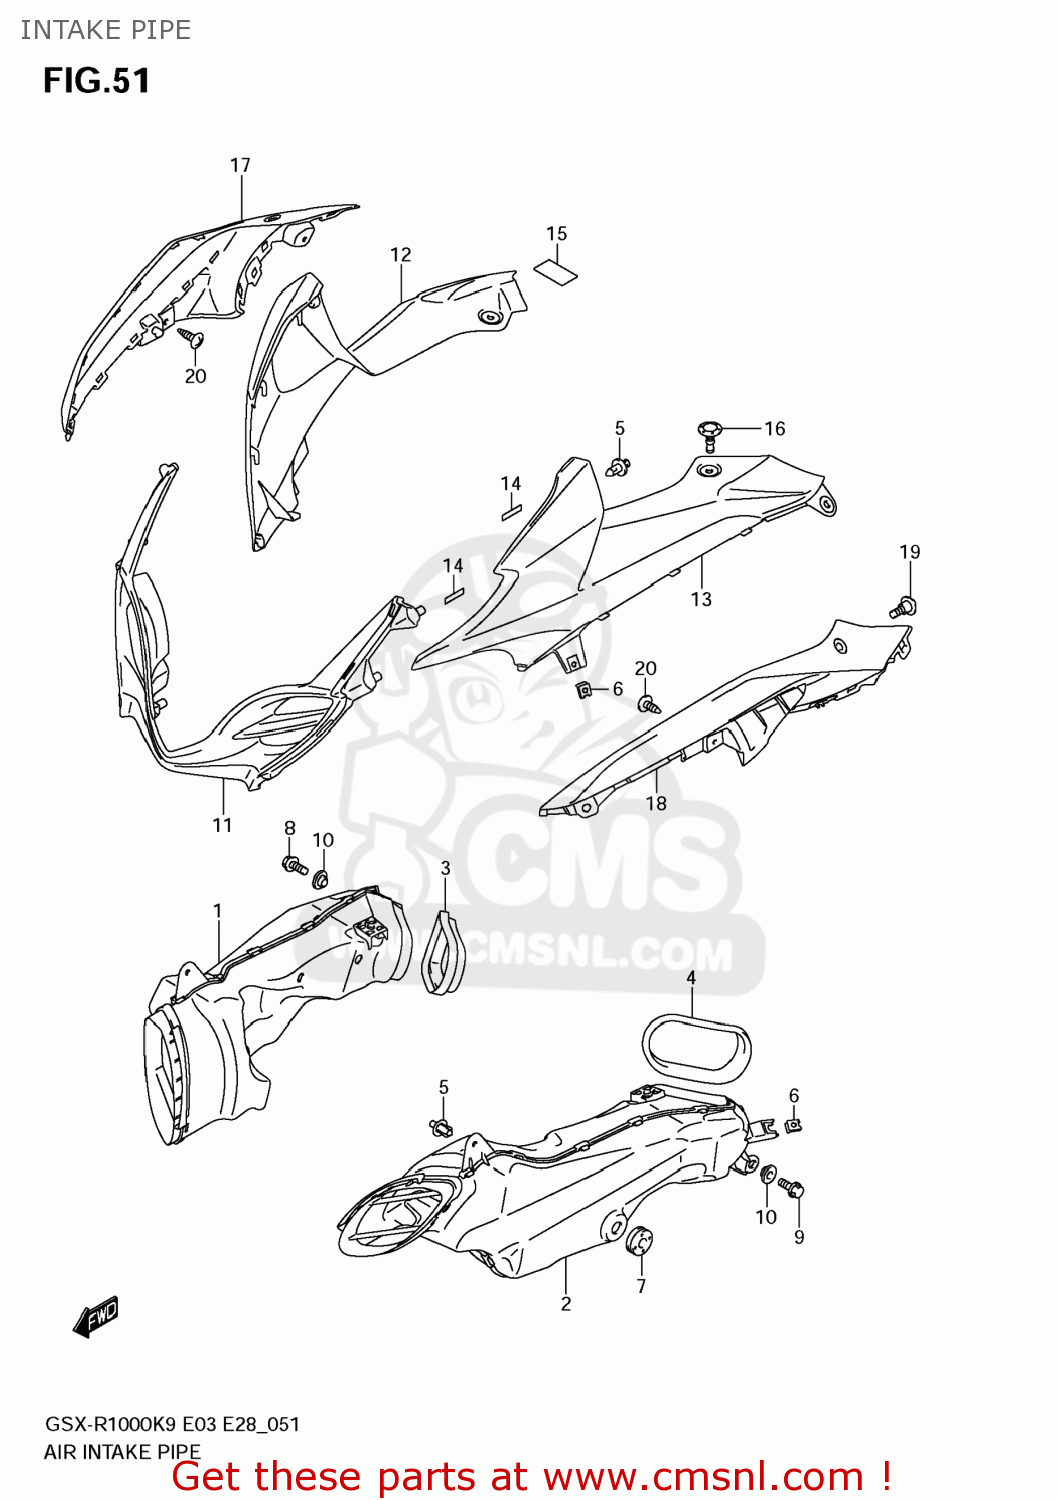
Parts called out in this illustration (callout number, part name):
1	PIPE,AIR INTAKE,R
2	PIPE,AIR INTAKE,L
3	MOLDING,AIR INTAKE,R
4	MOLDING,AIR INTAKE,L
5	CLIP(BLACK)
6	NUT
7	CUSHION
8	BOLT
9	BOLT
10	WASHER
11	COVER,INTAKE
12	COVER,INTAKE,R
13	COVER,INTAKE,L
14	TAPE(6X25X0.13)
15	PROTECTOR(30X80X1)
16	CLIP
17	COWLING,SIDE UPR,R
18	COWLING,SIDE UPR,L
19	SCREW(5X16)
20	SCREW
